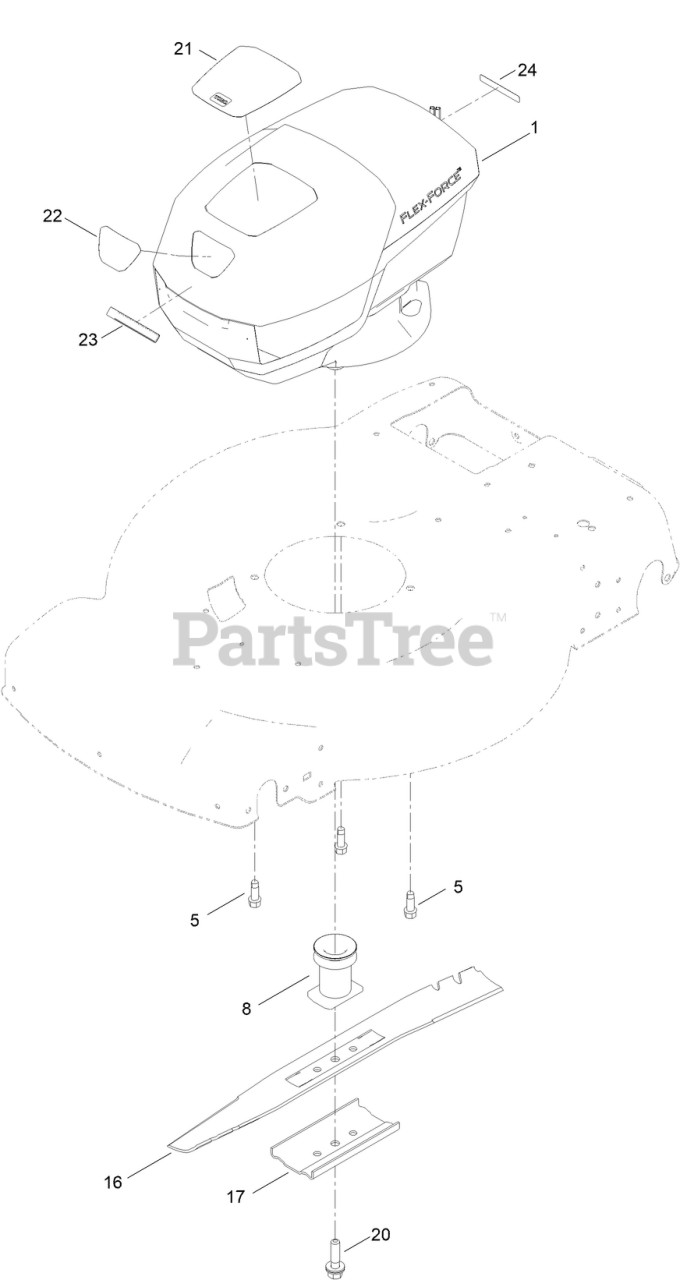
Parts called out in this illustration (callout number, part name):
1	MOTOR MODULE 60V
5	SCREW-THD FORM, HWH
8	DRIVER-BLADE
16	BLADE [BLACK]
17	SUPPORT-BLADE
20	BOLT-BLADE
24	DECAL-WARNING
